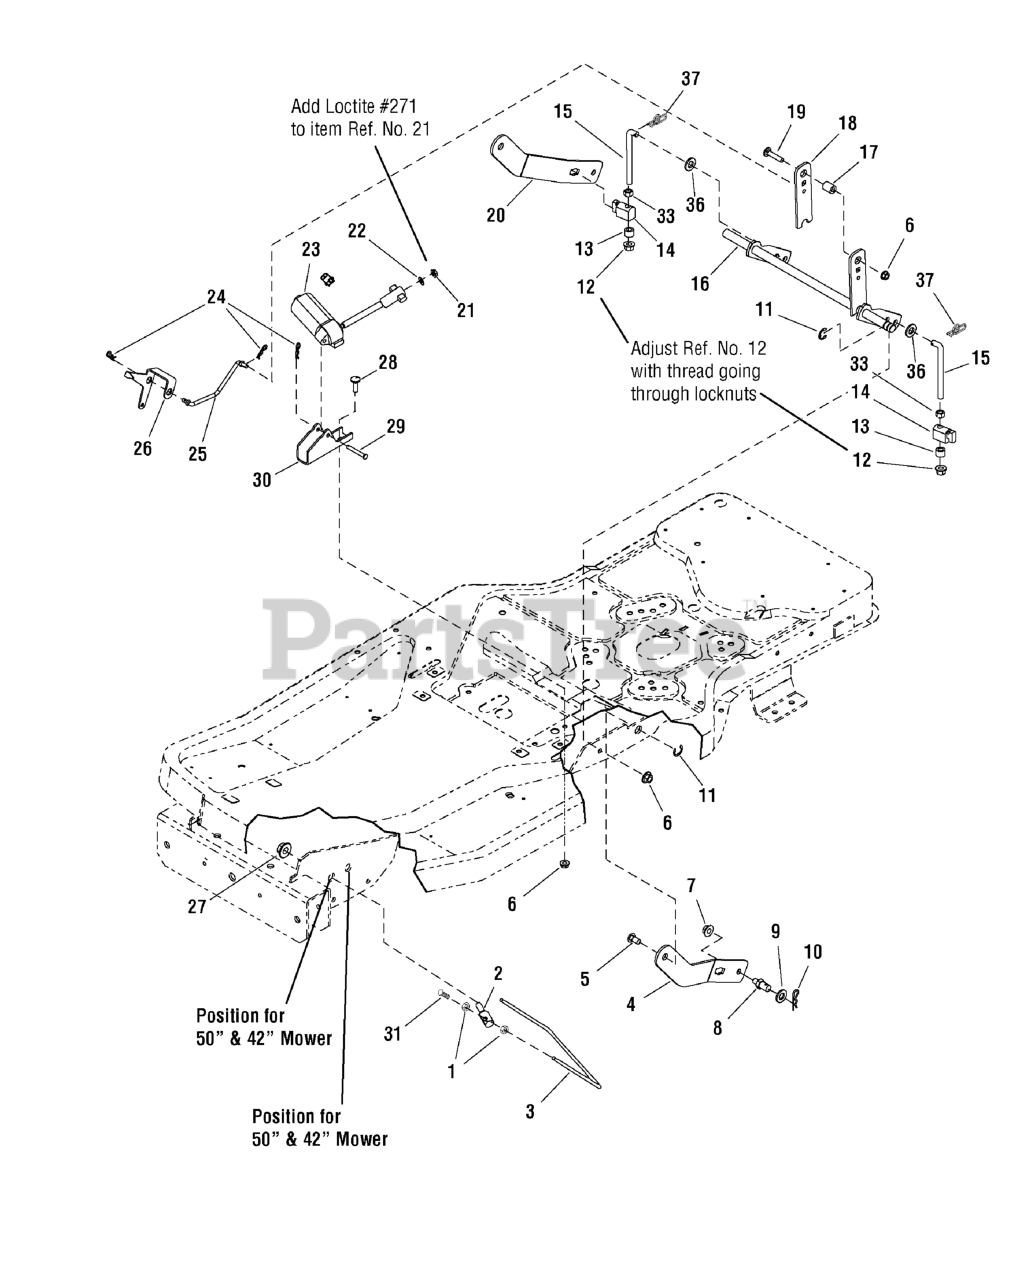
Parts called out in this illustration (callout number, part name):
1	NUT, Hex Jam, 7/16-14, NC-2B
2	TRUNNION
3	ROD, Bail
4	ARM, Mower Lift L.H.
5	BOLT, Shoulder
6	NUT, Hex Whiz Lock Flange, 5/16-18
7	NUT, Hex Whiz Lock Flange, 3/8-16
8	PIN, Threaded Shoulder
9	WASHER, 1/2"
10	CLIP, Hair Pin
11	RING, Klipring, 5/8"
12	NUT, Hex Flange, 3/8-16 ESNA
14	TRUNNION
15	ROD, Mower Lift 3/8-16 x 1 LG Thread
16	LIFT SHAFT ASSEMBLY
17	SPACER, Powdered Metal
18	ARM, Lift Trunnion
19	CARRIAGE BOLT, 5/16-18 x 1-1/2, G5
20	ARM, Mower Lift R.H.
21	NUT, Hex, 1/4-20 L.H. Thread
22	WASHER, 1/4"
23	MOTOR, Mini Actuator
24	PIN, Quick
25	ROD, Height of Cut Indicator
26	INDICATOR, Height of Cut
27	NUT, Hex Flange, Two-Way Lock, 1/2-13
28	BOLT, Carriage, Short Neck, 5/16-18 x 1
29	PIN, Shear
30	BRACKET, Electric Motor Mount
31	BOLT, Carriage, 3/8-16 x 3/4, G5
33	NUT, Hex 3/8 - 16
36	WASHER, 3/8
37	PIN, Cotter, Self Lock, 3/8
